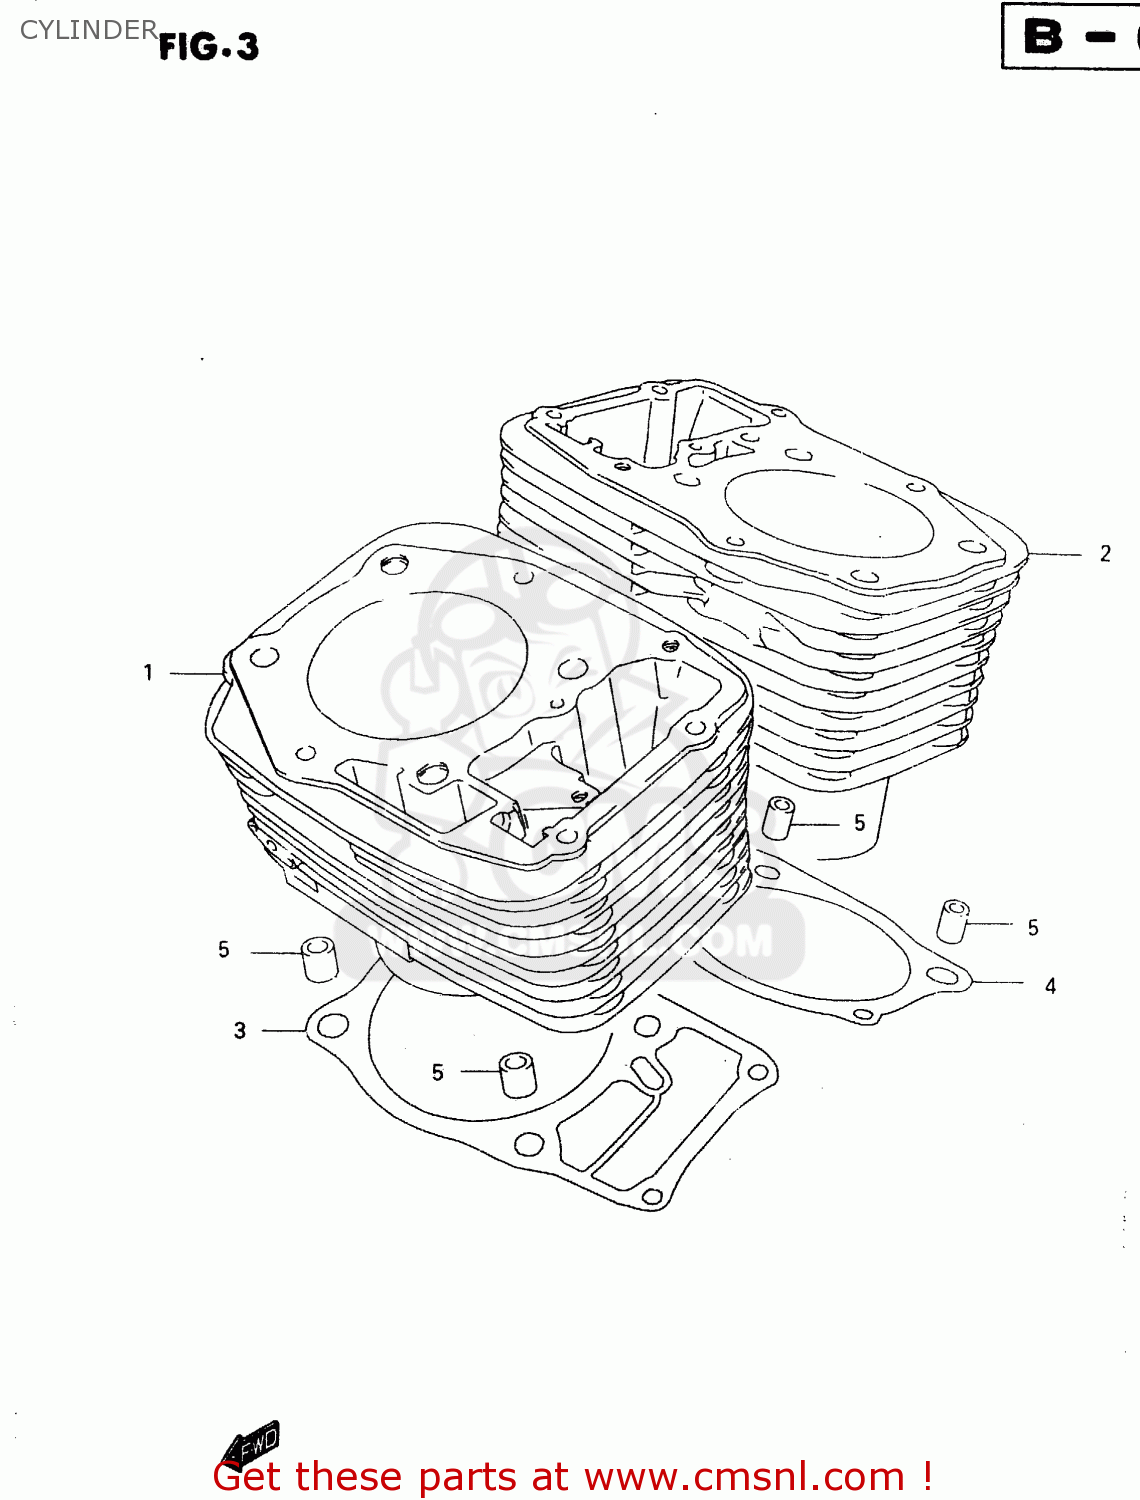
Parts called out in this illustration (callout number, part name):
1	CYLINDER,FR
2	CYLINDER,RR
3	GASKET,CYLINDER FR (NAS)
4	GASKET,CYLINDER RR (NAS)
5	PIN
